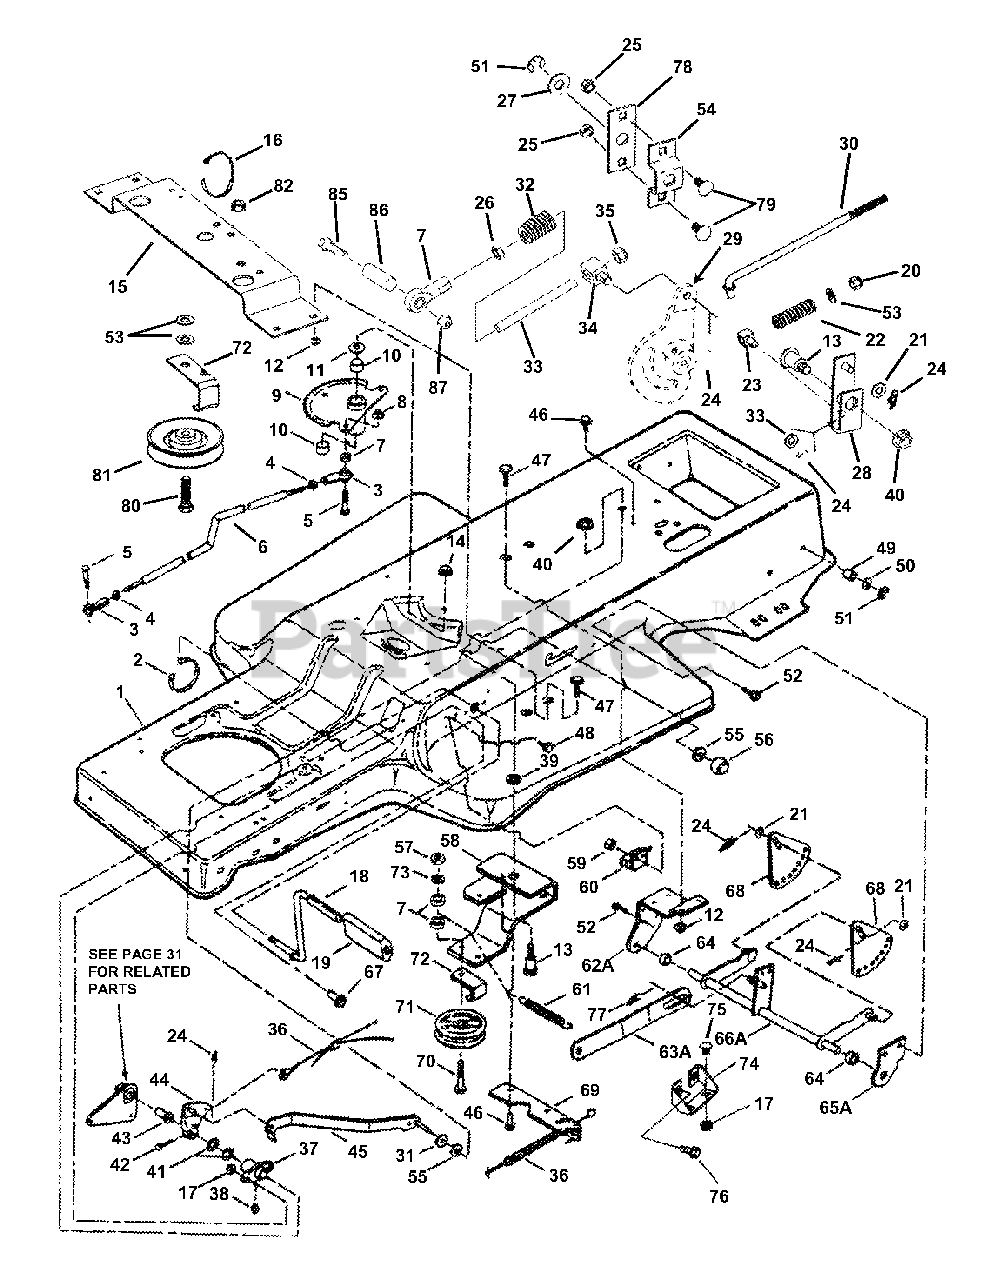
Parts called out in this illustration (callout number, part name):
1	FRAME, Tractor (1 piece)
2	TIE, Wire
3	BALL JOINT, Pump Control Linkage, 3/8-24 thread
4	NUT, 3/8-24 Hex Jam
5	SCREW, 3/8-24 x 1-1/4" Hex Cap
6	LINK, Drag
7	SPACER
8	NUT, 3/8-16 Hex Flange Lock
9	ASS'Y, Sector Gear
10	BEARING, Sector Gear
11	WASHER, 3/4" Thrust
12	NUT, 1/4-20 Hex Flange Lock
13	BOLT, 1/2-13 x 2" Shoulder
14	NUT, 1/2-13 Hex Center Lock Gr. A
15	BRACE, Sector Gear
16	TIE, Cable 7"
17	NUT, 5/16-18 Hex Flange Lock Gr. 5
18	PEDAL, Clutch Brake
19	PAD, Pedal
20	NUT, 3/8-16 Hex Nyloc
21	WASHER, 3/8 Bright Zinc, Flat
22	SPRING, Brake
23	SWIVEL, Inline Brake
24	PIN, 3/8 x 1-7/32" Cotter (Self-Locking)
25	NUT, 5/16-18 Hex Center Lock
26	NUT, 5/16-24 Hex Jam Lock
27	WASHER, .44" I.D. Flat
28	WELDMENT, Brake Arm
29	ARM, Speed Control
30	ROD, Brake
31	WASHER, 5/16" Flat
32	SPRING
33	WASHER, .406 I.D. Flat
34	SWIVEL, Brake Link
35	NUT, 5/16-24 Hex Top Lock
36	ASSEMBLY, Clutch/Brake Cable
37	ASSEMBLY, Foot Shaft Pivot
38	LUBE FITTING, Straight (press-fit for .187 dia. Hole)
39	WASHER, 1/2" Internal Tooth Lock
40	NUT, 1/2-13 Hex Flange Lock
41	WASHER, 5/8" Flat
42	PIN, 3/16 x 1-1/2" Clevis
43	BEARING, Flange
44	WELDMENT, Clutch Brake Arm
45	LATCH, Park Brake
46	SCREW, 5/16-18 x 5/8" Self-Tapping
47	BOLT, 1/4-20 x 5/8" Carriage
48	SCREW, #10-32 x 5/8" H.W.H.
49	BUSHING, 1/2" Nylon
50	WASHER, 1/2" Flat
51	RING, 1/2" External Retaining
52	SCREW, 5/16-18 x 5/8" Truss
53	WASHER, 3/8" Flat
54	BRACKET, Pivot Mounting
55	WASHER, 5/16" Nylon
56	KNOB, Clutch/Brake (5/16-18)
57	NUT, 3/8-16 Hex, Grade B or 5
58	ARM, Idler (Traction Drive)
59	NUT, #10-32 Hex Nyloc
60	SWITCH, DPDT NC/NO
61	SPRING, Traction Drive
62A	BRACKET, Rear Lift/PTO Lever
63A	LINK, Lift (Models: LT160H42GBV & LT160H42GBV2)
65A	BRACKET, Deck Hang Pivot
66A	WELDMENT, Rear Lift
67	SCREW, 5/16-18 x 7/8" Truss Head (Torx)
68	PLATE, Lift Sector
69	EXTENSION, Idler Arm
70	SCREW, 3/8-16 x 2-1/4" Cap Gr. 5
71	PULLEY, Flat Idler 3.47" O.D.
72	GUIDE, Pulley
73	WASHER, 3/8" Split Lock
74	BRACKET, Frame Brace
75	BOLT, 5/16-18 x 5/8" Short Neck Carriage, Grade 5
76	SCREW, 5/16-18 x 3/4" Self-Tap
77	COTTER PIN, 1/16 x 1-7/32" Self Lock
78	BRACKET, Mounting Brace
79	BOLT, 5/16-18 x 3/4" Carriage,
80	SCREW, 3/8-16 x 1-1/2" Cap, Grade 5
81	PULLEY, Idler V 3.30 HA
82	NUT, 3/8-16 Hex Center Lock
83	BALL JOINT, 5/16-24
84	ROD, Shift Linkage
85	SCREW, 5/16-18 x 1-1/2" Cap
86	SPACER
87	NUT, 5/16-18 Hex Center Lock
